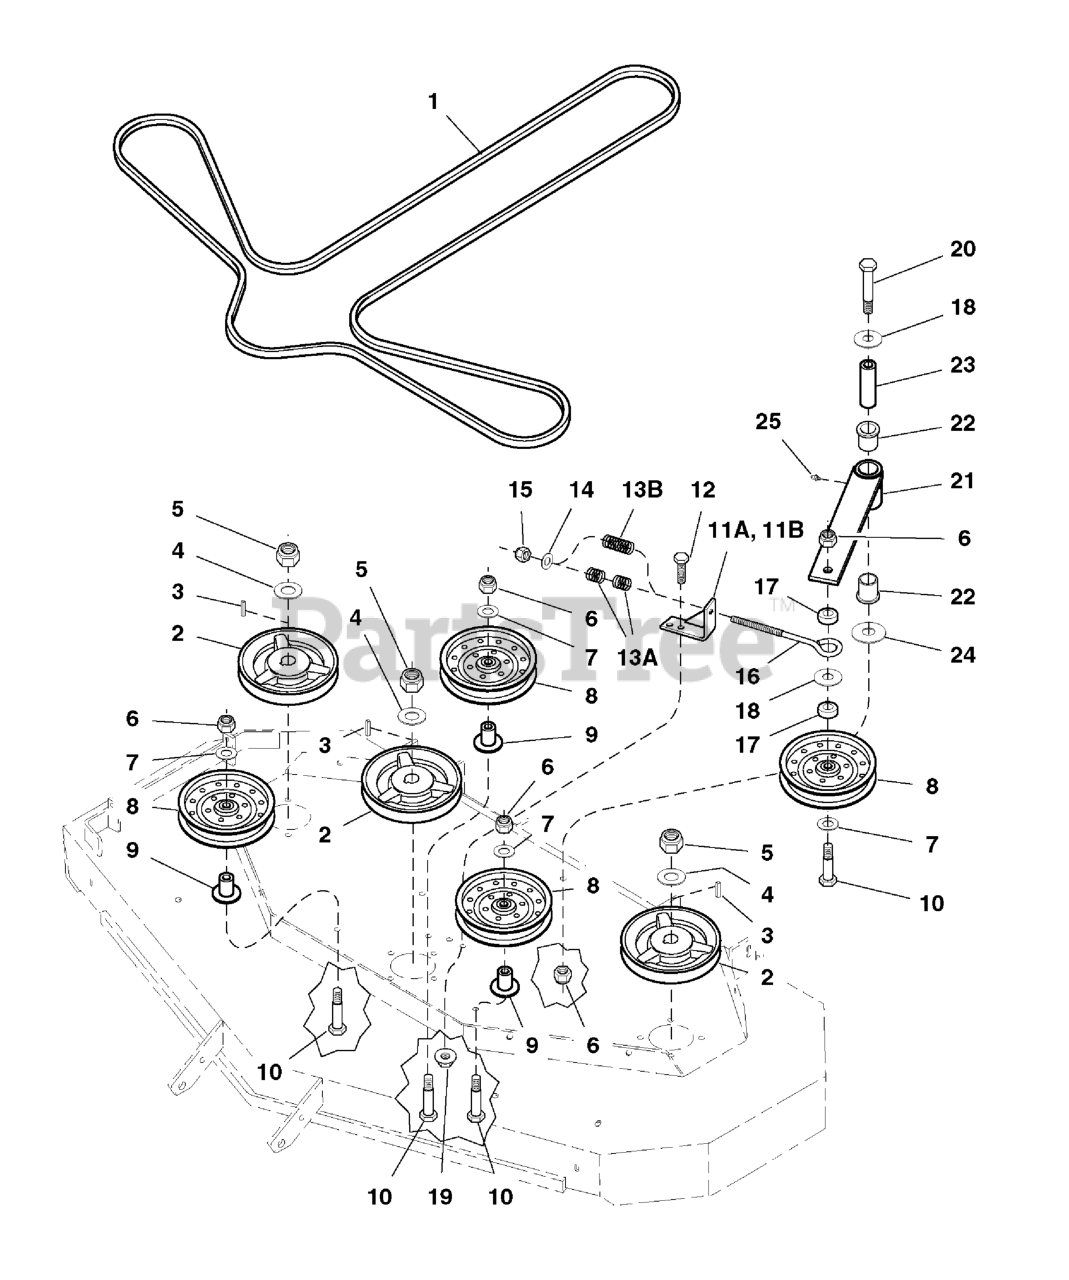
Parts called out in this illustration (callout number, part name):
1	BELT, 5V, 175.90EL, LG ARAMID, WRPD, RC
2	SPINDLE PULLEY
3	KEY, 1/4 SQ. X 1-1/4
4	WASHER, Spring
5	NUT, 5/8-18 Hex Nylon Lock
6	NUT, 1/2-13 HEX NYLON LOCK
7	WASHER, 1/2 SAE
9	IDLER MOUNT
10	BOLT, 1/2-13 X 3" GD5 CZ
11A	SPRING ANCHOR
11B	WELD, SPRING ANCHOR
12	BOLT, 3/8-16 X 1" GD5 CZ
13A	SPRING, Compression
13B	SPRING, Compression
14	WASHER, 3/8 SAE
15	NUT, 3/8-16 HEX NYLON LOCK
16	EYEBOLT, 3/8" x 8"
17	SPACER, .52 x 1.00 x .44
18	WASHER, 1/2" USS
19	NUT, 3/8-16 Hex Serrated Flange
20	BOLT, 1/2-13 x 4-1/2
21	IDLER ARM
22	BUSHING, FLANGE
23	SPACER, .52 x 1.00 x 3.50
24	WASHER, 5/8" SAE
25	GREASE FITTING
